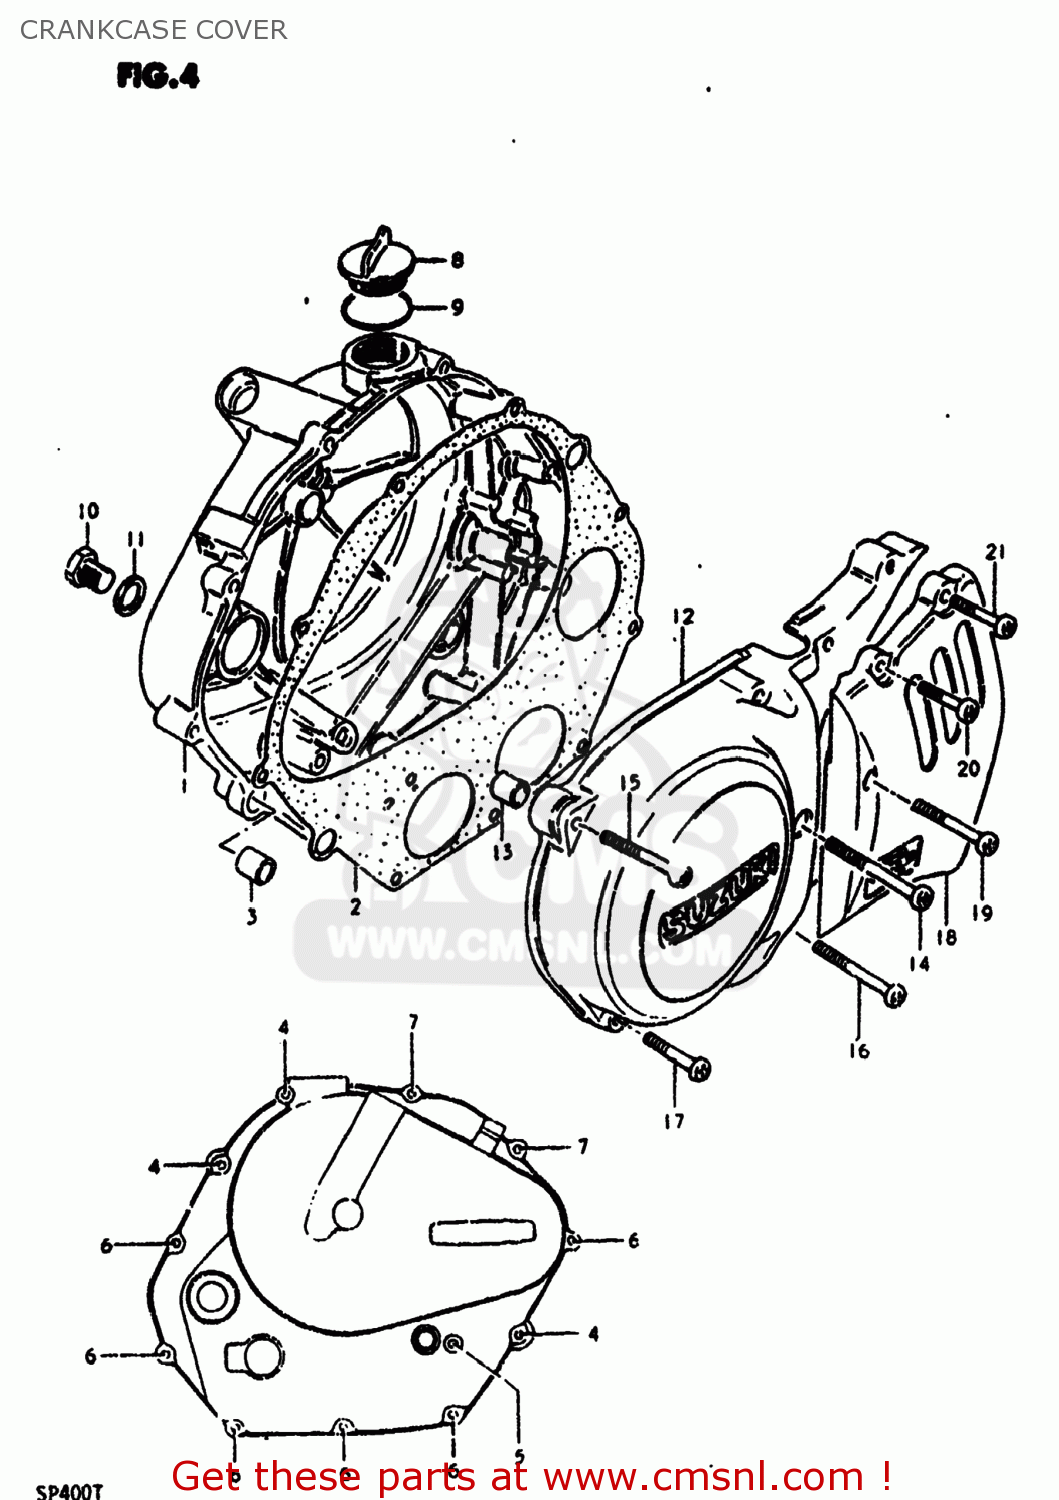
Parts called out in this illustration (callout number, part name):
1	COVER,CLUTCH
2	GASKET,CLUTCH COVER (MCA)
3	PIN
4	SCREW
5	SCREW
6	SCREW (6X35)
7	SCREW
8	CAP
9	O RING(D:2.2,ID:32)
10	PLUG (14X12)
11	GASKET(14X19.2X2) (NAS)
12	COVER
13	PIN
14	SCREW 6X60
15	SCREW
16	SCREW (6X45)
17	SCREW (6X35)
18	COVER,SPROCKET
19	SCREW
20	SCREW
21	SCREW
